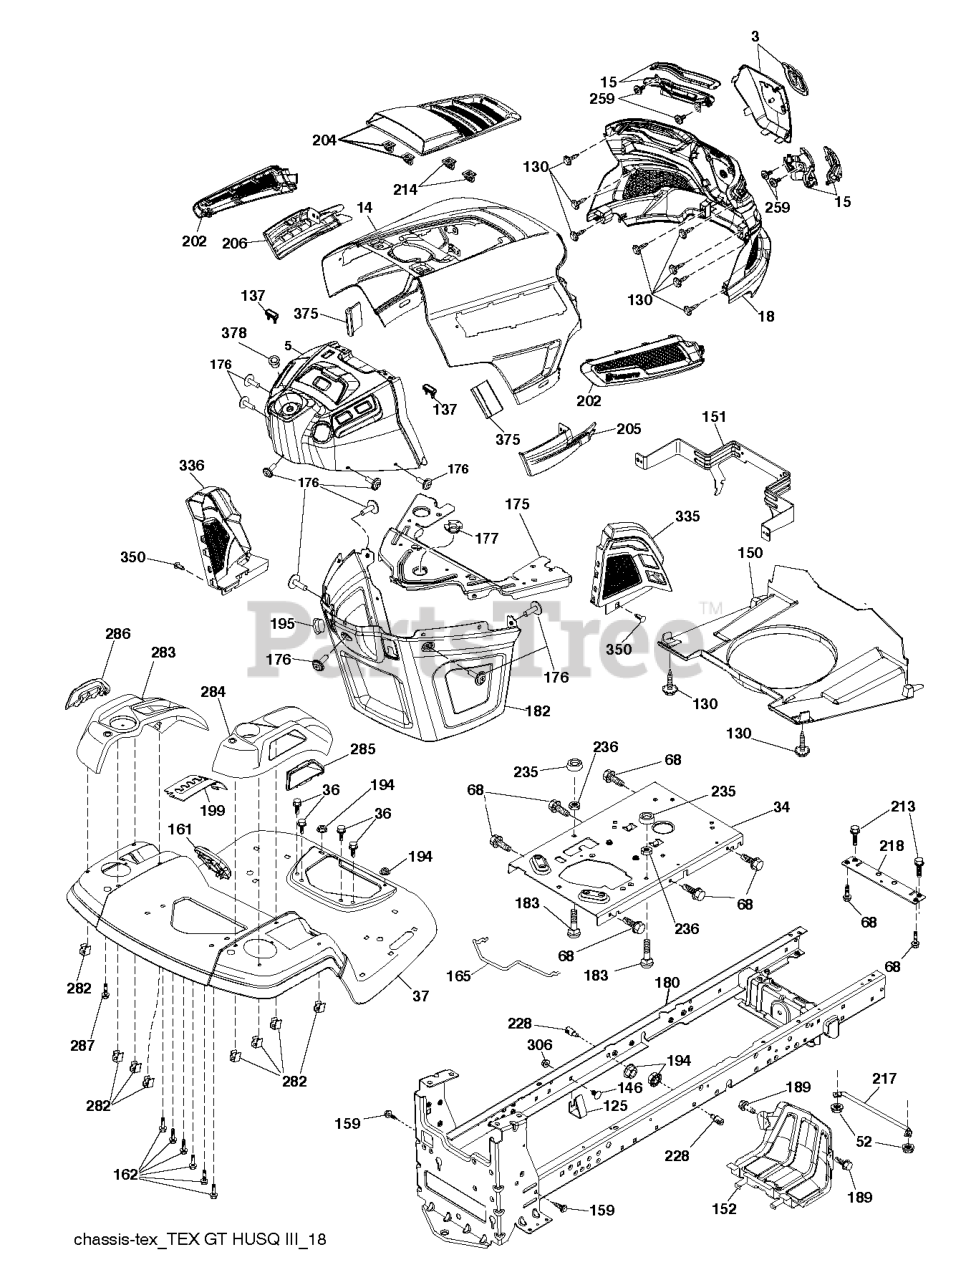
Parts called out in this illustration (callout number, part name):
5	DASH.UPPER.ASM.GT2.SRV.MND.MAN
14	KIT.HOOD.ASM.HUSQ.GT.TEX.668
15	Service Kit
34	PLATE.ENGINE.WELDED.CHASSIS
36	BOLT.5/16-18UNCX3/4 W/SEMS.BLK
37	FENDER.TLT.FS.W/CPH/FW/RSF.ORN
125	CLIP.FUEL.LINE
137	BUMPER DASH
146	BOLT.RDHD.SHT.SQNK.3/8-16X5/8
150	AIR.DUCT.GTV.BLACK
151	SERVICE KIT PIVOT BRACKET BRAC
152	SHIELD.BROWNING.PNT.GT.V2
159	SCREW, 3/8-16X3/4
161	WINDOW.FUEL.LT.HUSQ.TEX.498
165	SUPPORT.TANK.REAR.W/TEX
175	PLATE.PNT.CROSSMEMBER.HUSQ/PRE
176	SCREW.#10-24X5/8.RN.QU
177	BUSHING STEERING
180	KITS.CHASSIS.WELD.SERVICE
182	DASH.LOWER.COMMON.12V.ADAPTOR
189	BOLT.HEX.HD.WASHER.5/16-18X.75
195	PLUG.HOLE.DASH.LOWER.12V.BLK
199	PLATE.DECK.LIFT.HUSQ.LT
202	Vents
205	SIDE.TRIM.RH.GT.HUSQ.II
206	SIDE.TRIM.LH.GT.HUSQ.II.GRAY
213	SCREW HEXAGON HEAD SCREW 5/16-
214	CLIP.RETAINER.TINNER.
217	ROD.PIVOT.HOOD
218	X-PIECE.HOOD.STOP.NON/
228	STUD.W/"D"ANTI-ROTATION
236	NUT.CENTERLOCK.5/16-
282	CLIP.RETAINER.CONSOLE.LT.HUSQ
283	CONSOLE.DECK.LIFT.R.SDFL.HUSQ
284	CONSOLE.SHFT.PDL.CNTRL.HUSQ.LT
285	CONSOLE INSERT RH
286	CONSOLE.INSRT.LH.HUSQ.LT.BLACK
287	SCREW 1/4X20
306	NUT.HEX.FLANGE.3/8-16.LOCKNUT
335	COVER.LOWER.DASH.RH.BLACK
336	COVER-LH.LOWER.DASH.GT2.BLACK
350	CLIP.X-MAS.TREE
375	BUMPER CLIP-ON. DASH 1"
378	BUSHING FLANGE; PLASTIC
